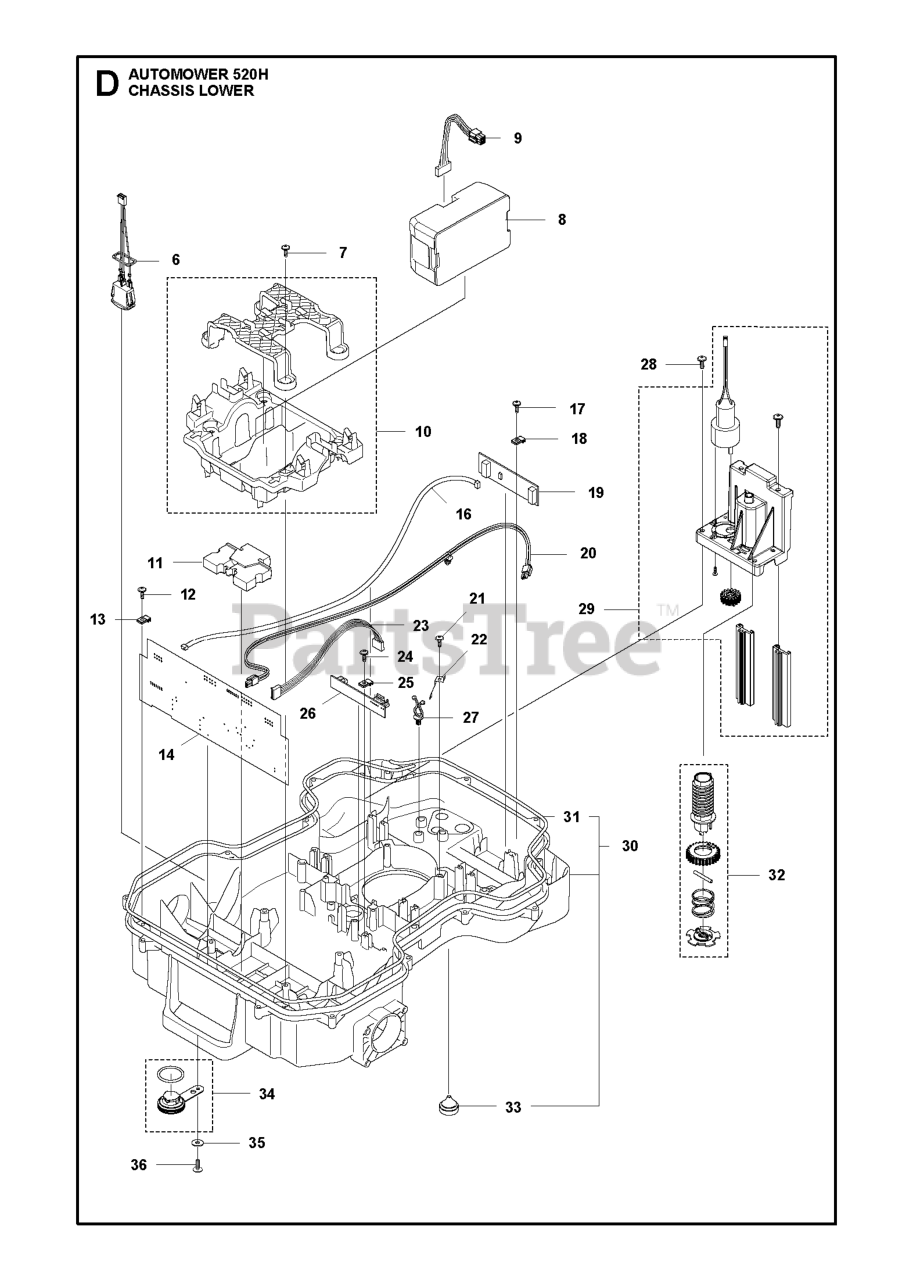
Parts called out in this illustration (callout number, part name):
6	LOOM ON/ OFF
7	SCREW ITXPANT
9	WIRING ASSY BATTERY CABLE
10	HOLDER KIT BATTERY
11	WEIGHT 470G
12	SCREW 14MM
14	PRINTED CIRCUIT ASSY PCBA MAIN
16	LOOM LOOP SENSOR
17	SCREW 14MM
19	PRINTED CIRCUIT ASSY LOOP SENS
20	LOOM CHARGING LINK HIGH CHARGI
21	SCREW 14MM
22	SPRING GUIDE HEIGHT ADJUSTMENT
23	LOOM HEIGHT ADJUSTMENT
24	SCREW 14MM
26	PRINTED CIRCUIT ASSY PCBA CUTT
27	HOLDER TWIST LOCK
28	SCREW 14MM
29	MOTOR ASSY HEIGHT MOTOR
30	CHASSIS KIT LOWER HI-CUT
31	SEALING STRIP
33	GROMMET M16
36	SCREW ITXPANT
